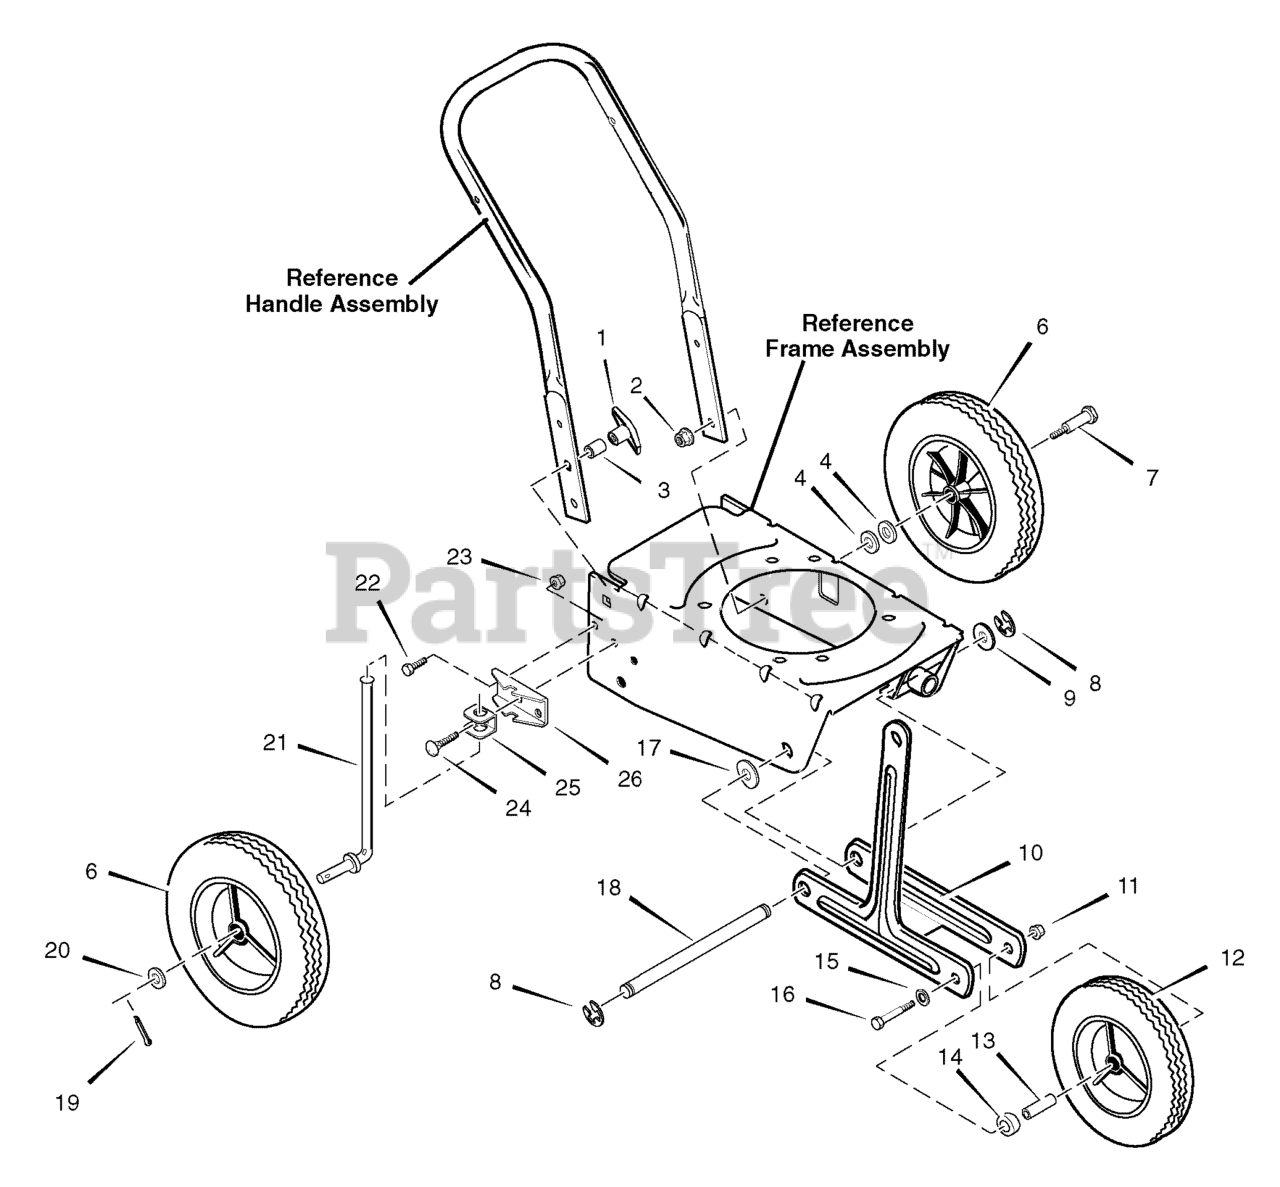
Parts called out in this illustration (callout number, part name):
1	KNOB, Wing
2	LOCKNUT, Flange
3	SPACER, Sleeve
4	WASHER
6	TIRE & RIM
7	BOLT, Shoulder
8	Ring, Ret E.
9	WASHER, Flat
10	ARM, Front Wheel
11	NUT, 5/16-18
12	TIRE & RIM
13	SPACER, Sleeve
14	WASHER, Nylon
15	WASHER, Flat
17	WASHER, Spring
18	ROD, Axle Front
19	PIN, Cotter
21	ROD, Wheel Support
22	SCREW, 5/16-18 x 0.75
23	NUT, 5/16-18
24	BOLT, 5/16-18x2.00
25	CLEVIS
26	BRACKET, Curb-Hop
